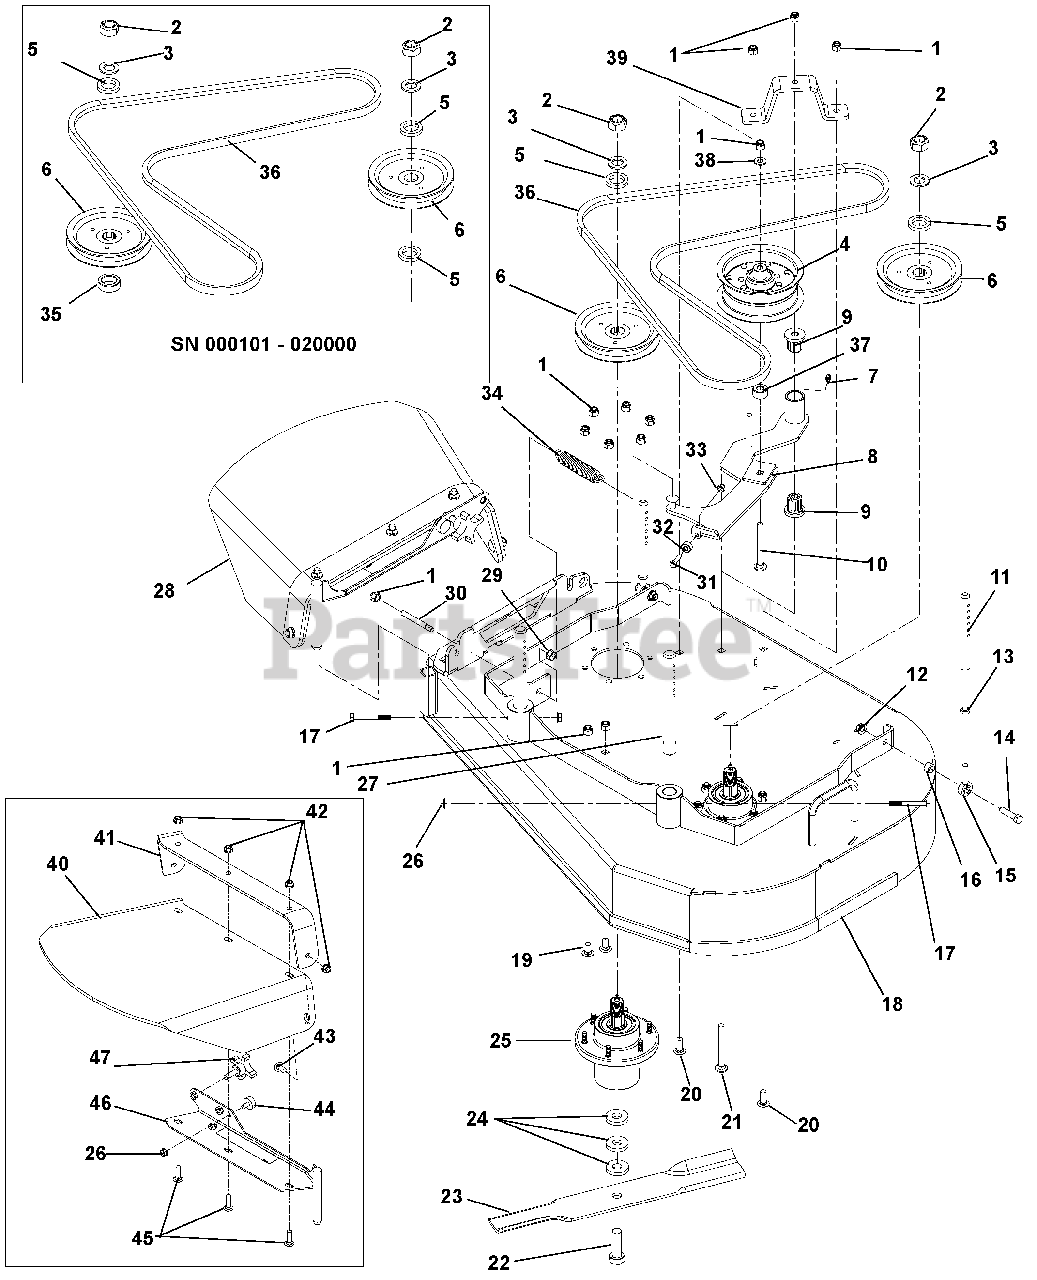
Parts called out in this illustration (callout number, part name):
1	NUT-LK-NYL .38-16
2	LOCKNUT, 3/4-16 CROWN GR 5
3	WASHER, .75 X 1.3125 X .113
4	PULLEY, FLAT 5.00 X 2.36 X .375
5	WSHR, FL-STL 1.0 X 1.5 X .25 (SSN 000101 - 020000)
6	PULLEY, SPLINE SPINDLE SHFLWLK (SN 000101 - 020000)
7	FTG, 1/4-28 STRGT GREASE ZERK
8	WLDT, IDLER ARM 36 (SN 000101 - 020999)
9	BRG, FLG M10 X M25 X M27 FLUTED
10	BOLT, RDHDSQNK .38-16X3.50 GR5Y
11	ROD, REAR HOC
12	NUT, LK TOP FLG .375-16 YWZC REV (SN 000101 - 020999)
13	NUT, JAM .375-24 YWZC REV
14	BOLT, HEX .38-16 X 1.50 GR5 (SN 000101 - 020999)
15	ROD, END 3/8 RH REV
16	BSHG - SLV REV
17	BOLT, 5/16-18X2.50 HEX 8
18	ASSY, 36" FLWLK DECK W/DECALS (SN 000101 - 020000)
19	BOLT, RDHDSHSQNK .38-16 X .75 G5
20	BOLT, RDHDSQNK .38-16X1.00 G5
21	BOLT, RDHDSQNK .38-16X3.50 GR5
22	BLT-HEX .62-11X 2.00 GR8 YWZC
23	BLADE, 18"
24	WASHER, FLAT-STEEL .630 x 1.50 x .25
25	ASSY, SPINDLE HOUSING
26	NUT-SPNLK-FLG .312-18
27	PIN, HOC
28	ASSY, DISCHARGE SHIELD
29	NUT-SPNLK-FLG .375-16
30	ROD, THREADED ADJUSTMENT (SN 000101 - 021000)
31	BOLT, HEX .25-20 X 1.00 GR5
32	BRG, BAL .250 X .688 X .313
33	NUT-LK-NYL .250-20
34	SPRING, EXT .875 X .125 X 4.25 Y (SN 000101 - 020999)
35	SPACER, 1.500 X 1.000 X .510 Y (SN 000101 - 020000)
36	BELT, HB 85.1 EL AMD
37	SPACER, .437 X 1.00 X .58 SMLS
38	WASHER, .406 X .813 X .065 FLAT Y
39	STRAP, IDLER 36
40	SHIELD, WALK RUBBER DISCHARGE
41	STRAP, GRAVELY WLK RUBBER DIS
42	NUT, SPNLK-FLG .375-16
43	BOLT, RDHDSQNK .38-16 X 1.00 G5
44	BUMPER, RUBBER
45	BOLT, RDHDSQNK .38-16 X 1.25 G5
46	WLDT. DISCHARGE
47	KNOB, 3/8 X 1.25 - 4 PRONG
